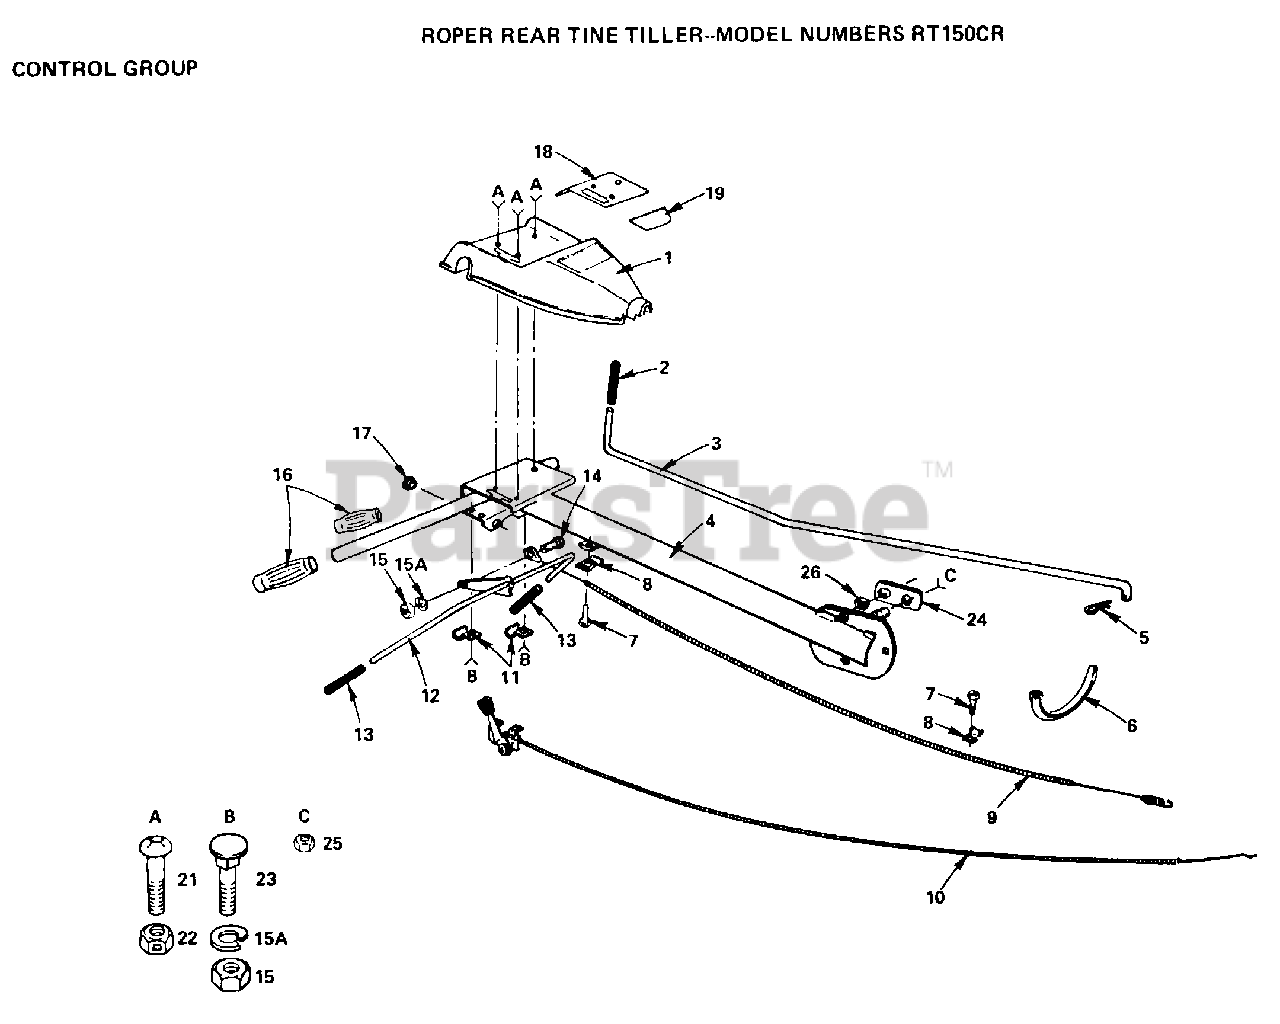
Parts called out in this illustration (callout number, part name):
1	PANEL - CONTROL
2	GRIP TI
5	RETAINER M
6	TIE CABLE CRT
7	SCREW TI
8	CONDIUT CLIP T
9	CABLE.CLUTCH.CRT
10	CTRL-THROTTLE T
13	GRIP BAR CRT
14	SHOULDER BOLT ST
15A	LOCKWASHER
17	GROMMET TI
19	DECAL - CONTROL PANEL
23	BOLT
24	"NUT, LOCK CRT"
25	LOCKNUT
26	NUT FLANGE CRT
